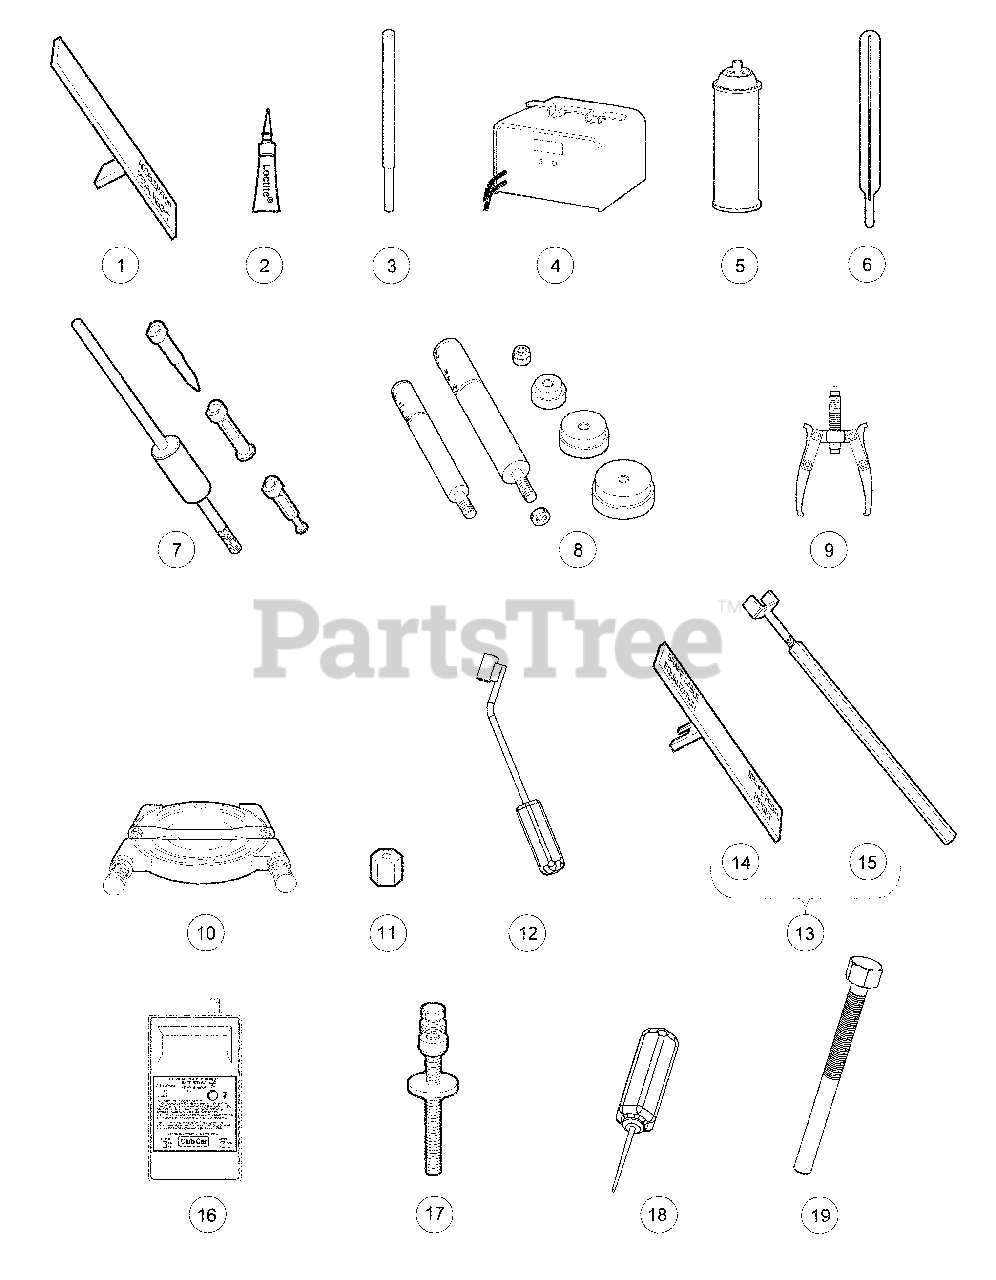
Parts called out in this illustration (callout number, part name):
1	Accelerator Pedal Adjustment Tool
2	Adhesive, Guide Ring, 3-Gram Tube
4	Battery Discharge Machine, 36/48 Volt
5	Battery Terminal Protector Spray
6	Battery Thermometer
7	Bearing and Oil Seal Remover Assembly
8	Bearing Driver Set
9	Bearing Puller
10	Bearing Puller Wedge Attachment
11	Brake Adjustment Tool
12	Brake Cable Release Tool
13	Brake Pedal Adjustment Tool Kit
14	Brake Pedal Adjustment Tool
15	Brake Pedal Tension Tool
16	Calibration Test Module
17	Cam Installation Tool
18	Charger Bezel Tool
19	Clutch Removal Tool (for 4x4 vehicles)
20	Clutch Tool Kit
21	Clutch Alignment Tool
22	Drive Clutch Puller
23	Drive Clutch Hub Puller
24	Driven Clutch Cam Puller
25	Driven Clutch Puller Plug
26	Drive Clutch Holder Tool Assembly
27	Press Weldment
28	Drive ClutchFixed Sheave Tool (for 4x4 vehicles)
29	Driven Clutch Spring Compression Base (for 4x4 vehicles)
30	Driven Clutch Spring Compression Collar (for 4x4 vehicles)
31	Driven Clutch Spring Compression Nut (for 4x4 vehicles)
32	Drive Clutch Spider Removal Tool (for 4x4 vehicles)
33	Communication Display Module
34	Compression Gauge and Adapter
35	Continuity Tester
36	Cutter, Valve Seat, #122
37	Cutter, Valve Seat #115
38	Wrench, T, #505
39	Adapter, T-Wrench
40	Cutter, Valve Seat, 60 Degree
41	Pilot, 6.6 MM
42	Pilot, 6.62 MM
43	Pilot, 6.65 MM
44	Dry Moly Lubricant
45	Flywheel Puller Kit
46	Gauge, Carburetor Float Level
48	Governor Shaft Installation Tool
49	Hydraulic Brake Adjuster (for HUV 4213)
50	Hydrometer
51	Internal Retaining Ring Pliers
52	IQ Display Module (IQDM) Kit
53	IQ Display Module (IQDM-P) Kit
54	Adaptor, Cable
55	IQDM Series 2 Cable
56	IQDM Series 1 Cable
57	Liquid Gasket
58	Moly-Teflon Lubricant (4-oz. (113-gram) tube)
59	Paint, Touch-Up – Beige
59	Paint, Touch-Up – Black
59	Paint, Touch-Up – Burgundy
59	Paint, Touch-Up – Classic Blue
59	Paint, Touch-Up – Dark Gray
59	Paint, Touch-Up – Dark Green
59	Paint, Touch-Up – Gray
59	Paint, Touch-Up – Red
59	Paint, Touch-Up – Royal Blue
59	Paint, Touch-Up – White
60	Paint, Precedent Underbody – Gray
61	Paint Pen, Touch-Up, Precedent Underbody – Black
62	Piston Ring Compressor Kit (FE290, FE350 and FE400 engines)
63	Piston Ring Pliers
64	Puller, Special Use
65	Retaining Ring Pliers, 45° External
66	Retaining Ring Pliers, 90° Internal
67	Safety First Card (50 per pack)
68	Seal Puller
69	Spanner Wrench
70	Steering Column Bearing Press Tool
71	Steering Column Retaining Ring Tool
72	Steering Wheel Puller Tool
73	Tachometer
74	Tachometer Diesel Probe
75	Transaxle Axle Seal Tool
76	Transaxle Pinion Seal Tool
77	Transmission Tool Kit
82	Valve Clearance Adjuster Screw Holder
83	Valve Guide Driver
84	Valve Guide Reamer (FE290, FE350, and FE400 only)
85	Valve Guide Reamer, 6.6 mm
86	Valve Seat Cutter Guide
87	Valve Seat Cutter T-Wrench
88	Valve Seat Cutter, 45° (32 mm diameter) (for FE290 engines only)
89	Valve Seat Cutter, 45°/30° (35 mm diameter)
90	Valve Spring Compressor
91	Volt Ohm Meter
92	Tool, Tensioning, Starter Generator
